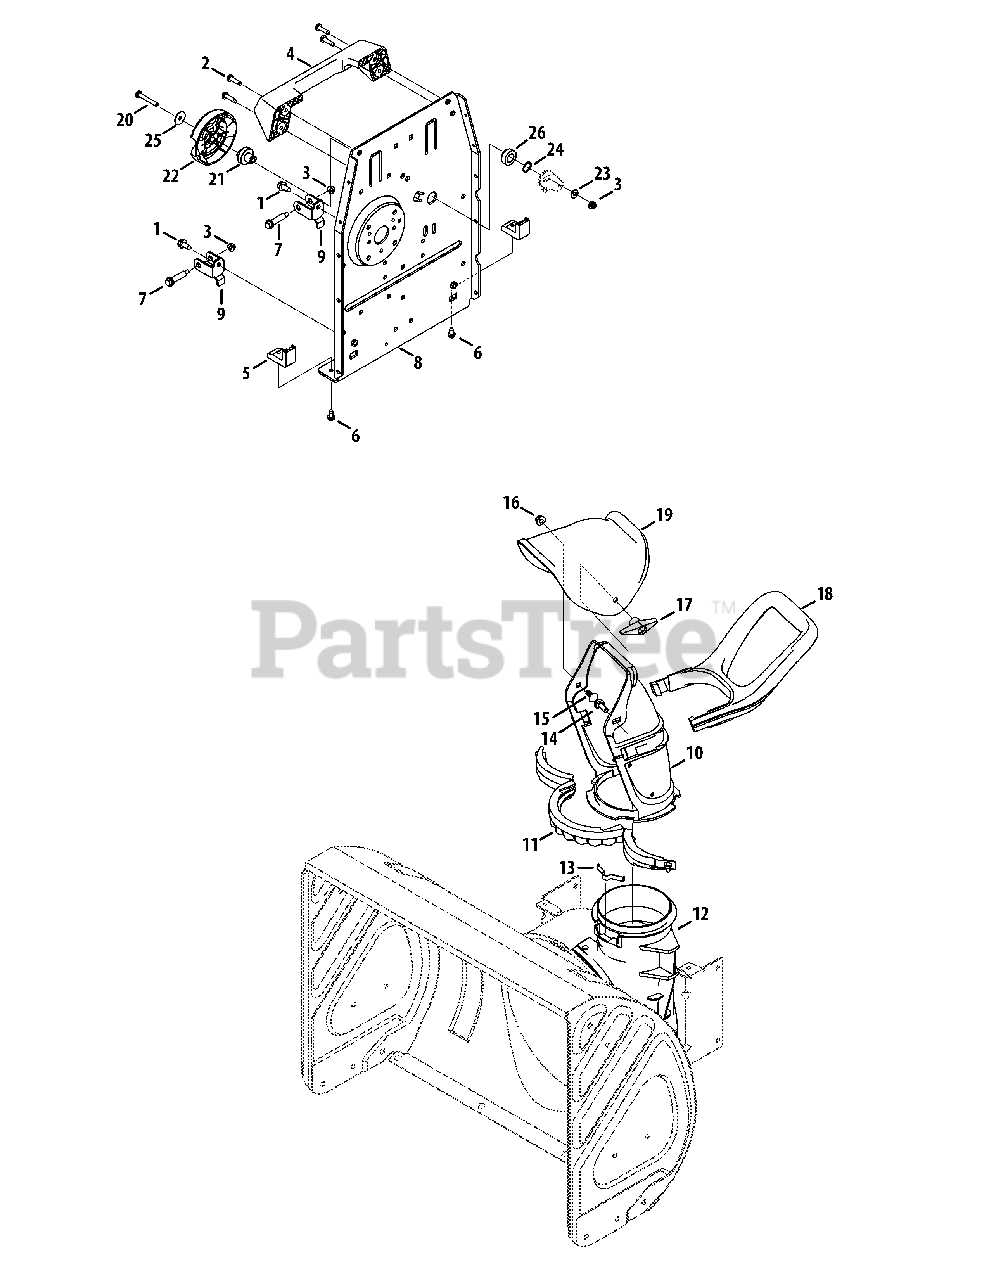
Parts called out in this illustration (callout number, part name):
1	Hex Washer Screw, 5/16-18 x .750
2	Self-tapping Screw, 1/4-20 x 1.00
3	Flange Lock Nut, 1/4-20
4	Rear Handle
5	Bumper Pad
6	Shoulder Screw, 1/4-20 x 0.50
7	Shoulder Screw,, 1/4-20 x .375 x 1.355
8	Frame Mounting Bracket
9	Support Bracket
10	Lower Chute, 5" Diameter
11	Lower Chute Ring
12	Chute Adapter
13	Chute Adjustment Spring
14	Carriage Bolt, 5/16-18 x 1.00
15	Carriage Bolt, 5/16-18 x 0.75
16	Flange Lock Nut, 5/16-18
17	Wing Knob, 5/16-18
18	Chute Handle
19	Upper Chute
20	Hex Cap Screw, 1/4-20 x 1.75
21	Clutch Link Shaft
22	Idler Clutch
23	Bell Washer, .265 x .75 x .062
24	Wave Washer, .65 ID x .855 x .010
25	Flat Washer, .265 x 1.0 x .030
26	Hex Flange Bearing 5/8 PM
